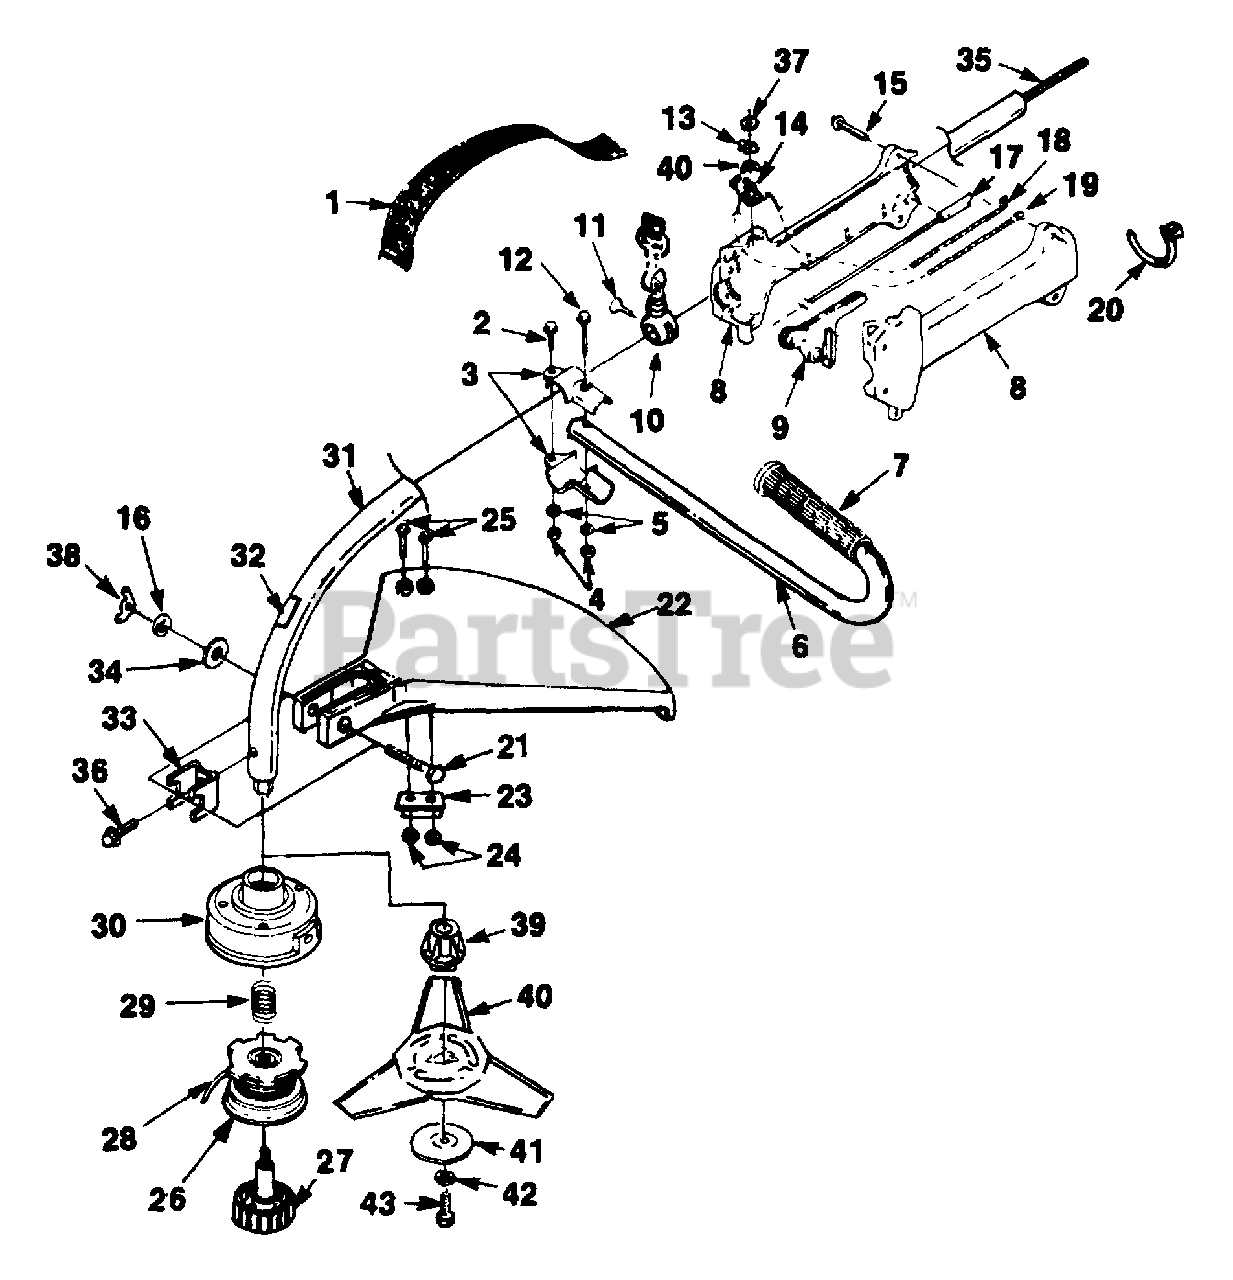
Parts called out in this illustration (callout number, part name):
1	HARNESS w/CONNECTOR
2	SCREW (1/4-20 X 7/8")
3	CLAMP-Handle Bar
4	NUT (1/4-20)
5	WASHER (1/4")
6	HANDLE BAR
8	HANDLE GRIP ASSEMBLY
9	TRIGGER
10	BRACKET-Hanger
11	SCREW-Thumb
12	SCREW (1/4-20 X 1 1/2")
13	PLATE-Indicating
14	SWITCH-Toggle
15	SCREW-Plastite (#8 X 3/4")
16	WASHER-Lock (1/4")
17	CABLE-Throttle
18	LEAD-Electrical
19	LEAD-Ground
20	CABLE-Tie
21	SCREW-Cap Hex Hd. (1/4-20 X 2")
22	DEFLECTOR-Grass
23	BLADE-Cut-Off
24	NUT (10-24)
25	SCREW-Mach Hex Hd (10-24 X 7/8")
26	SPOOL & STRING
27	SPOOL RETAINER
28	LINE-Replacement (.095 dia)
29	SPRING-Compression
30	HOUSING & EYELET
31	HOUSING-Driveshaft
32	DECAL-Warning
33	CLAMP
34	WASHER-Flat
35	SHAFT-Flexible
36	SCREW-Thread Forming
37	NUT-Toggle Switch
38	NUT-Wing
39	ADAPTOR-Blade
40	TRI-ARC BLADE
41	WASHER-Cupped
42	WASHER-Lock
43	SCREW-Cap Hex Hd
